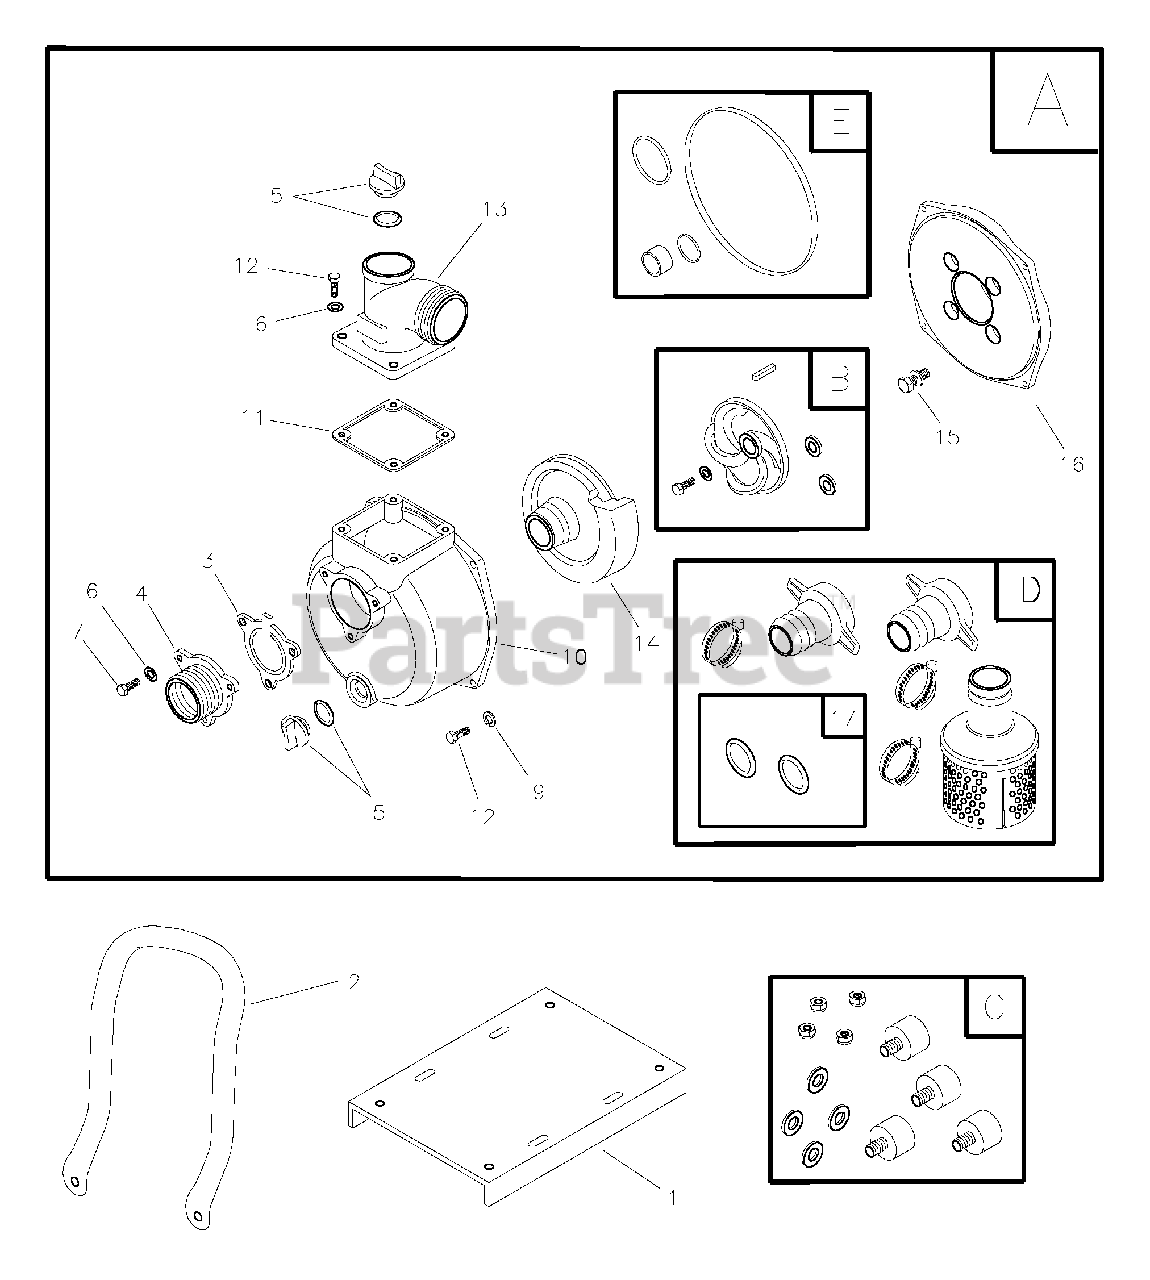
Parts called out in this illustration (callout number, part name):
4	FLANGE, Inlet, 2" NPT
6	WASHER, Flat, 5/16 - M8
7	CAPSCREW, Hex Head, M8 - 1.25 x 16
9	WASHER, Lock 5/16 - M8
12	CAPSCREW, Hex Head, M8 - 1.25 x 25
13	FLANGE, Out, 2" NPT
16	ADAPTER, Engine
A	ASSY, Housing Pump
B	KIT, Impeller 2"
C	KIT, Vibration Mount
D	KIT, Coupler 2" NPT
